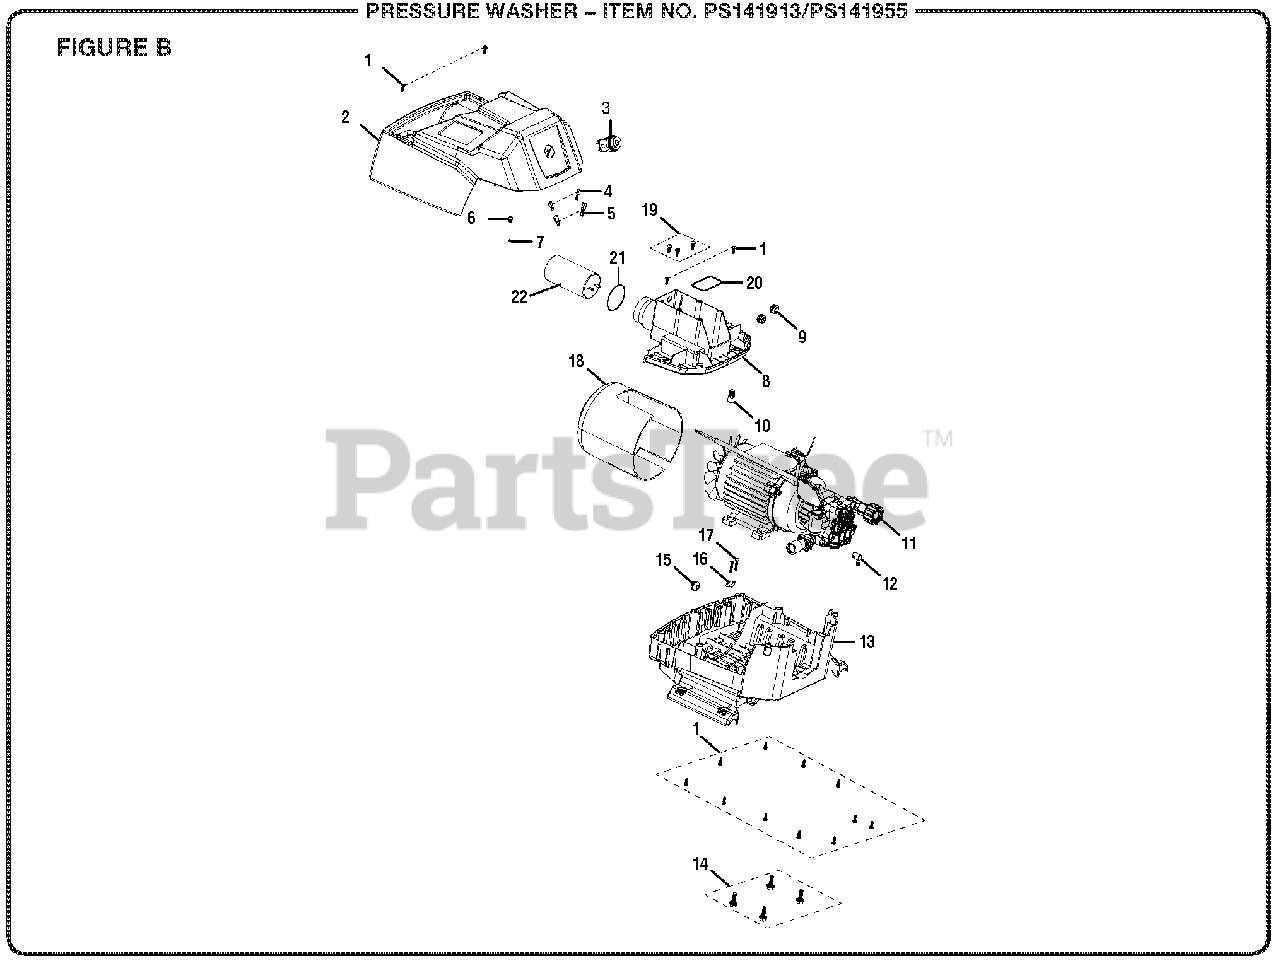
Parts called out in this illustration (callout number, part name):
1	Screw (M4.2 x 15 mm, Pan Hd.)
2	Top Motor Housing
4	Tinned Brass (Terminal)
5	Plastic Sleeve (Terminal)
6	Screw (M4 x 6 mm, Pan Hd.)
7	Toothed Lock Washer (M4)
8	Pump Cover
11	Motor and Pump Assembly
12	Soap Hose Inlet Adapter
13	Lower Housing
14	Bolt (M6 x 20 mm)
16	Cord Clamp
17	Screw (M3.5 x 20 mm)
18	Nozzle (15deg)
19	Bolt (M4 x 12 mm, Pan Hd.)
20	Rubber Ring
22	Capacitor
